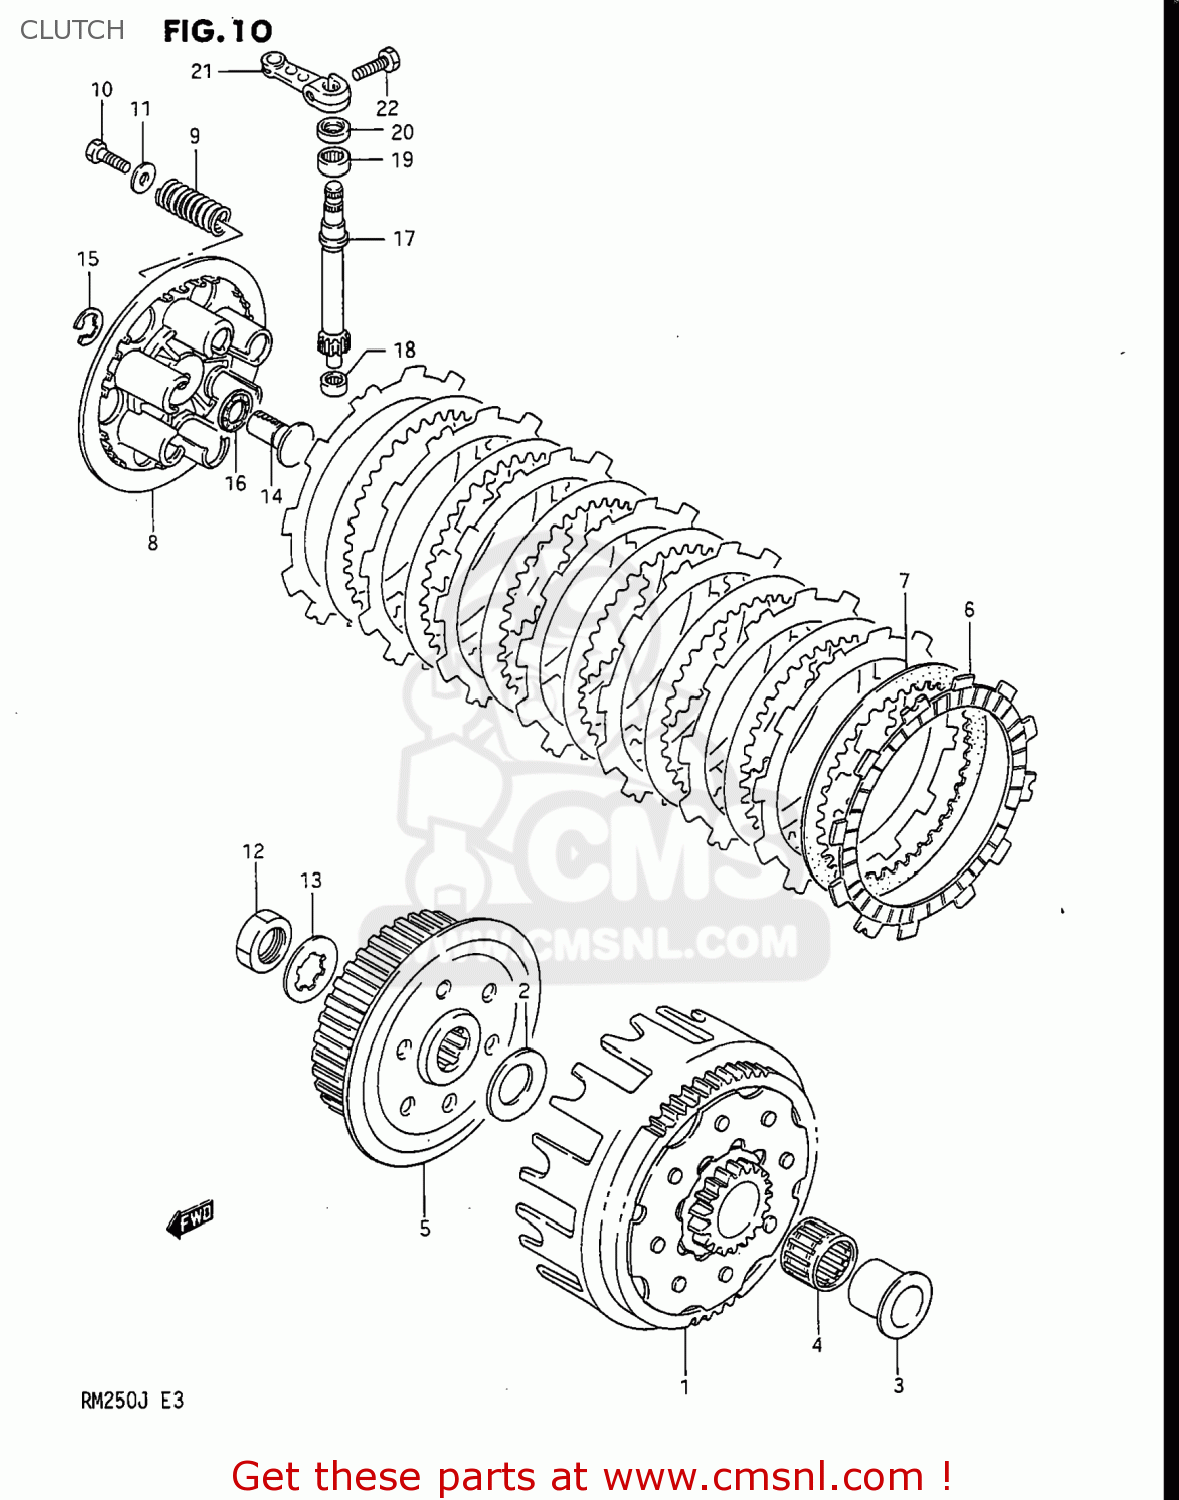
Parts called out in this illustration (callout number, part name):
1	GEAR ASSEMBLY,PRIMARY DRIVE
2	WASHER(20X36X2)
3	SPACER,PRIMARY DRIVEN
4	BEARING(25X30X22)
5	HUB,CLUTCH SLEEVE
6	PLATE,CLUTCH DRIVE (NAS)
7	PLATE,CLUTCH DRIVEN (NAS)
8	DISC,CLUTCH PRESSURE
9	SPRING
10	BOLT(5X16)
11	WASHER
12	NUT (20MM)
13	WASHER,LOCK
14	RACK,CLUTCH RELEASE
15	E RING 8MM
16	BEARING(10X22X2.8)
17	PINION,CLUTCH RELEASE(NT:12)
18	BEARING(9X13X10)
19	BEARING(12X16X10)
20	SEAL,OIL(10X17X5)
21	ARM,CLUTCH RELEASE
22	BOLT
